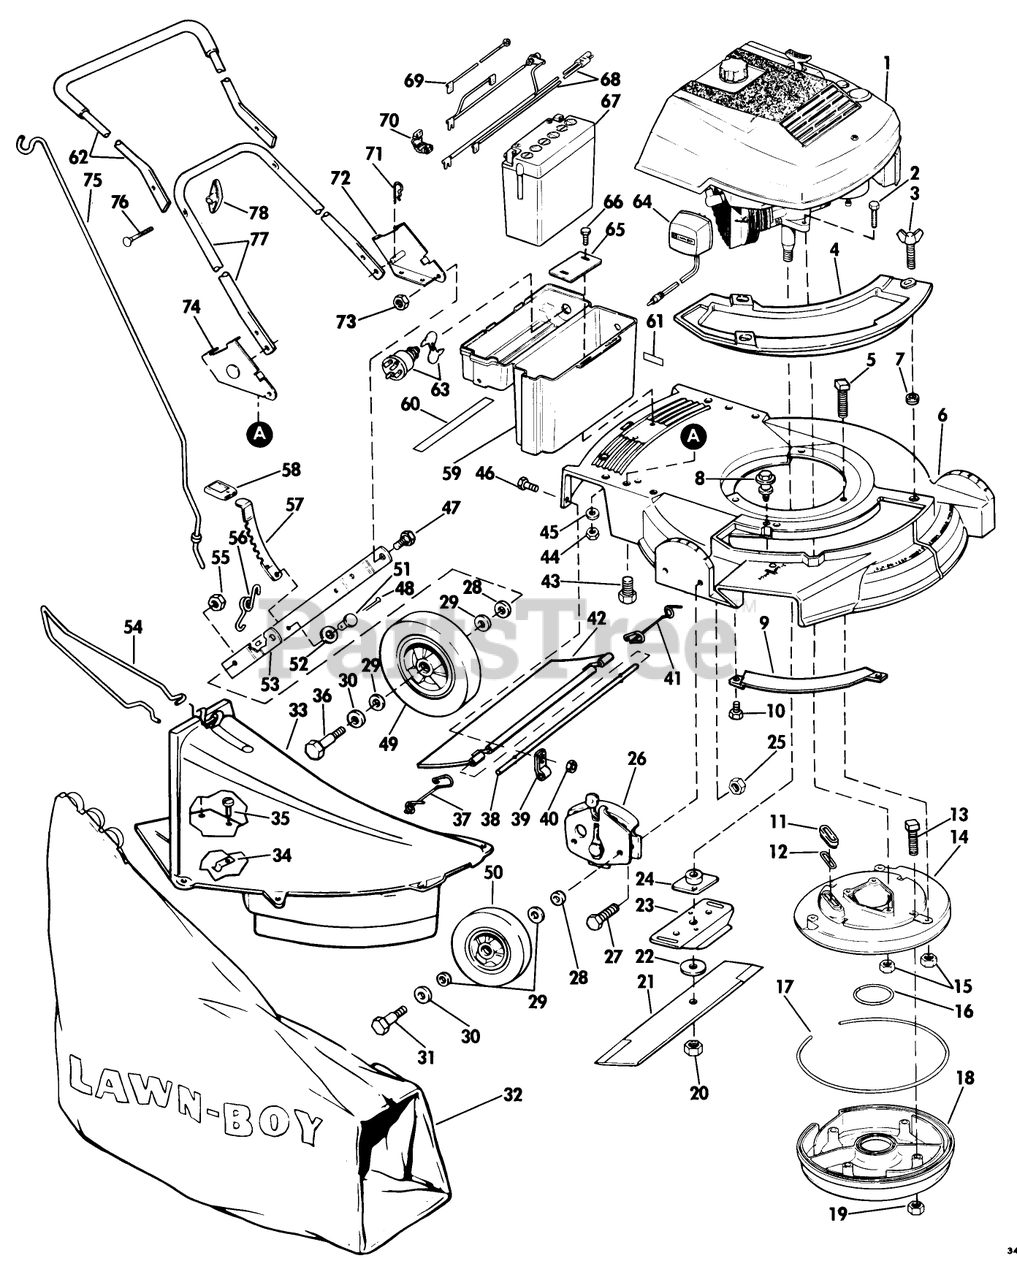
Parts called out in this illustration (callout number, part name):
3	WING SCREW LAWRE
5	SCREW V
9	BAR-TOE
12	GASKET S
15	NUT-LOCK F
17	Gasket Muffler (outside)
19	LOCKNUT E
20	NUT-BLADE
24	PLATE AND COLLAR ASM
28	WASHER WROUGHT
31	BOLT WHEEL
32	ORD LB 89802 WHOLE GOODS
37	SPRING;TRAILING SHIELD RH
38	ROD 21" ADVANCE
39	CLAMP ROD KMC
41	SPRIG T/SHLD ASOC
43	SCREW
47	BOLT-SHOULDER
52	WASHER SPRING LAR
55	LOCKNUT
56	SPRING N.A.S
64	BATTERY CHARGER
71	HAIR PIN
75	ROD GRASSBAG
78	NUT-WING
